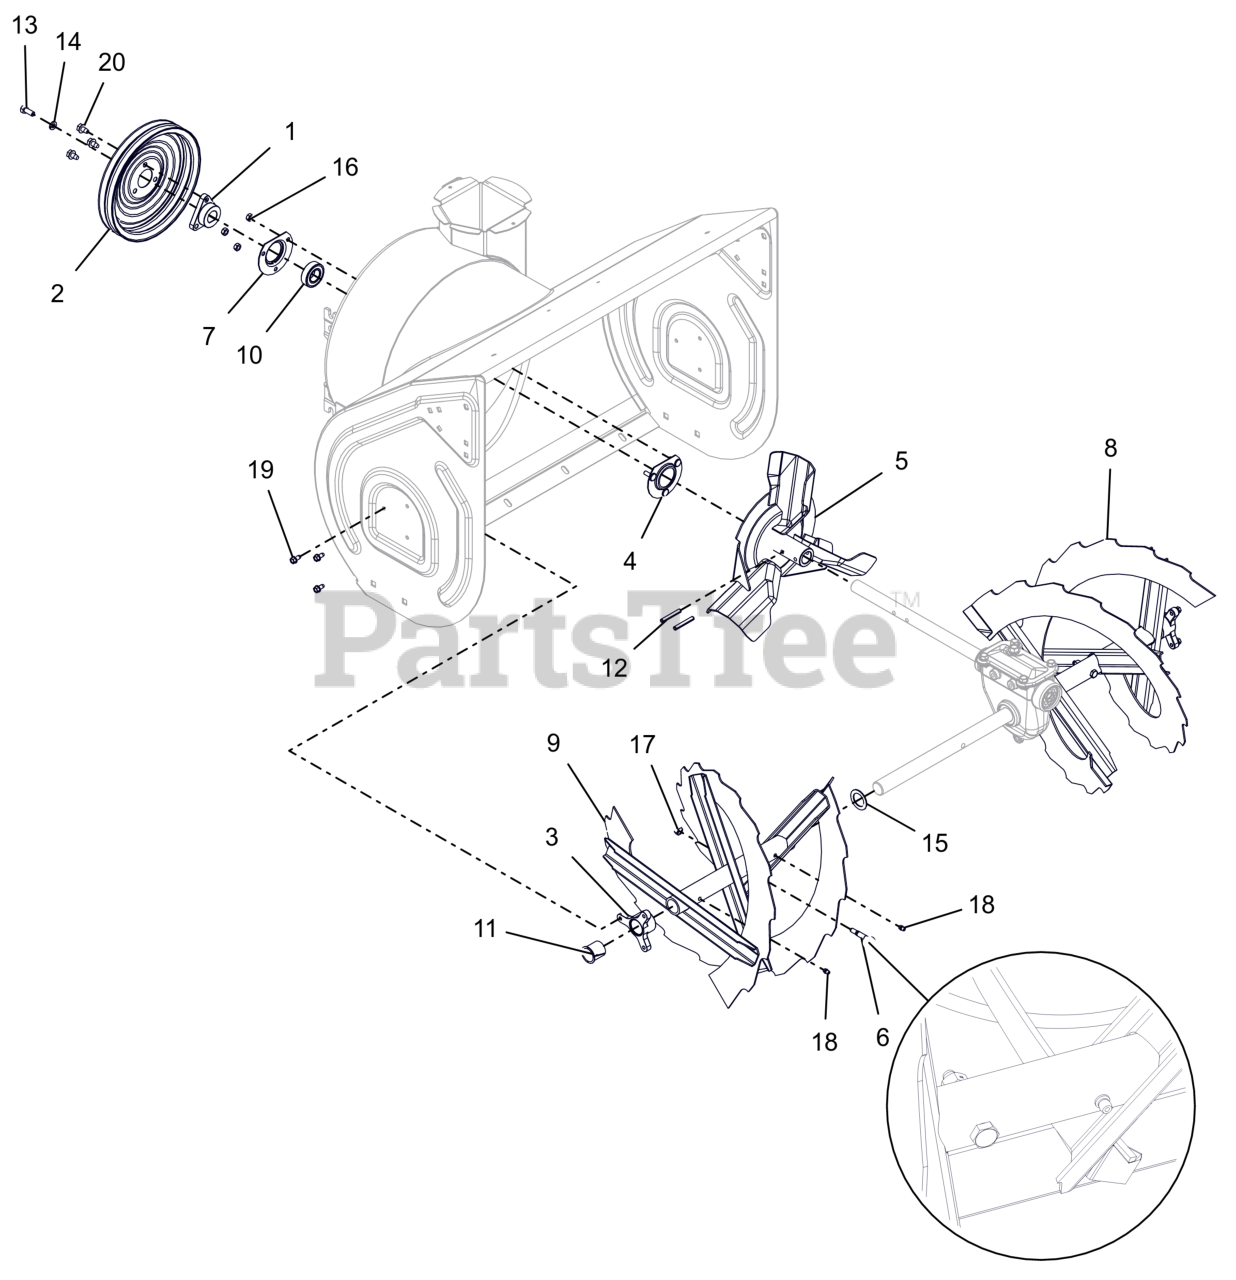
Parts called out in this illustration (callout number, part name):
1	PULLEY HUB, D-BORE .87 PRO
2	PULLEY, SPIN FORM DUAL GROOVE
3	BUSHING, RAKE SHAFT 1"
4	BEARING FLANGE
5	IMPELLER, 3 BLADE-14"
6	SHEAR BOLT SERVICE ASSEMBLY
7	BEARING FLANGE
8	RAKE, LH-28"(1 ID X 15.75 OD)
9	RAKE, RH-28"(1 ID X 15.75 OD)
10	BRG-BALL .876X1.75X.50 RSTFP
11	BSHG-FLG SPLIT NYLINER 1.0" HP
12	PIN-ROLL .250X1.75
13	BLT, HEX .31-24X.750 G5 ZCC
14	WSHR, LK-HVY .312X.097 ZCC
15	WSHR, FLT 1.010X1.505X.062 ZCC
16	NUT,LK-CTR .25-20 GA ZCC
17	NUT,LK-CTR .31-18 GA ZCC
18	ZERK,FITTING .25X.125 DRIVE IN
19	SCR-TAP .25-20X.50 HWH ZCC
20	SCR,TAP .312-18X.50 HWH TR ZCC
